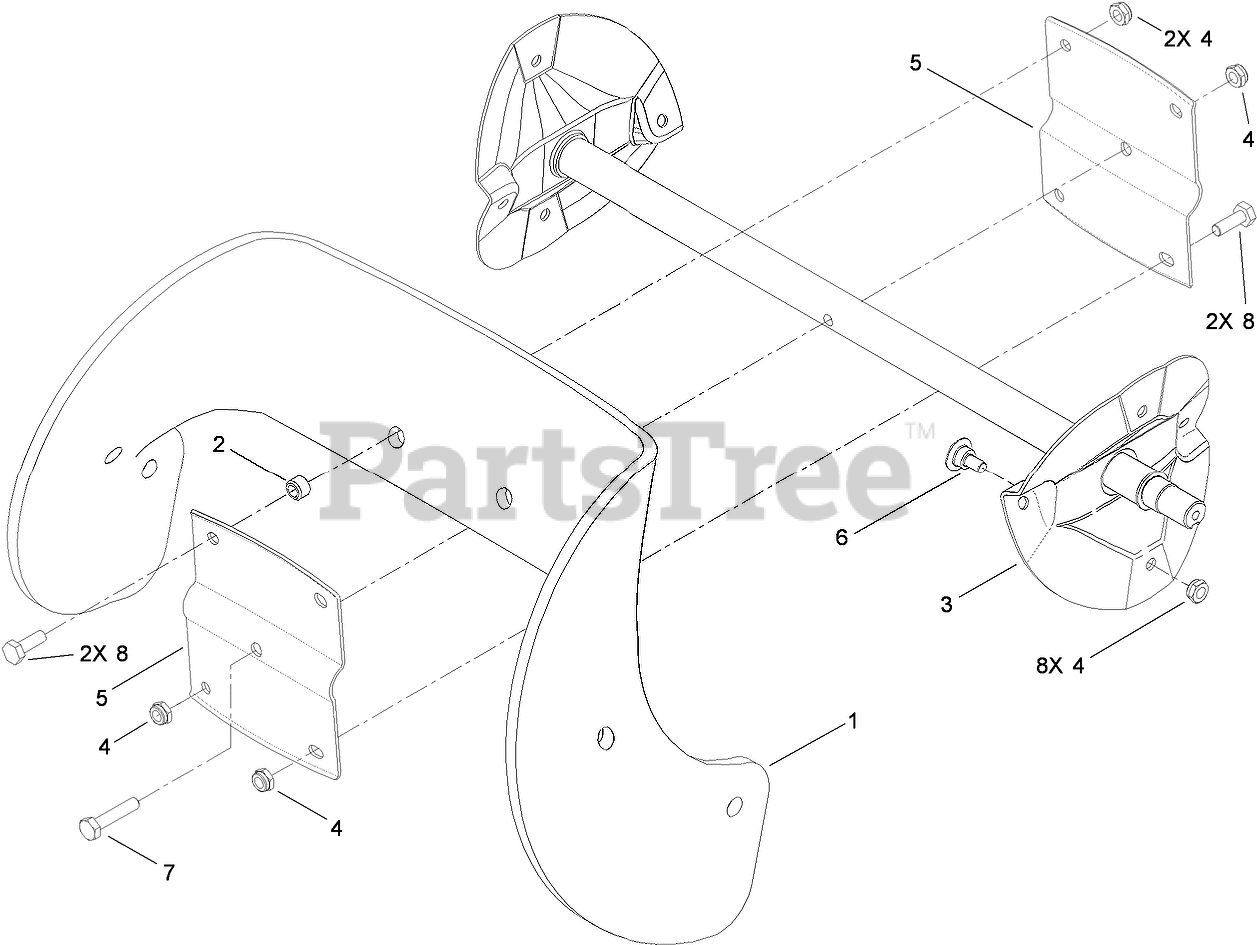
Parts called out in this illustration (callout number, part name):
1	BLADE-ROTOR
2	SPACER-BLADE, ROTOR
3	ROTOR ASM
4	NUT-LOCK, NI
5	HALF-ROTOR
6	SCREW
7	SCREW-HH
8	SCREW-HH
